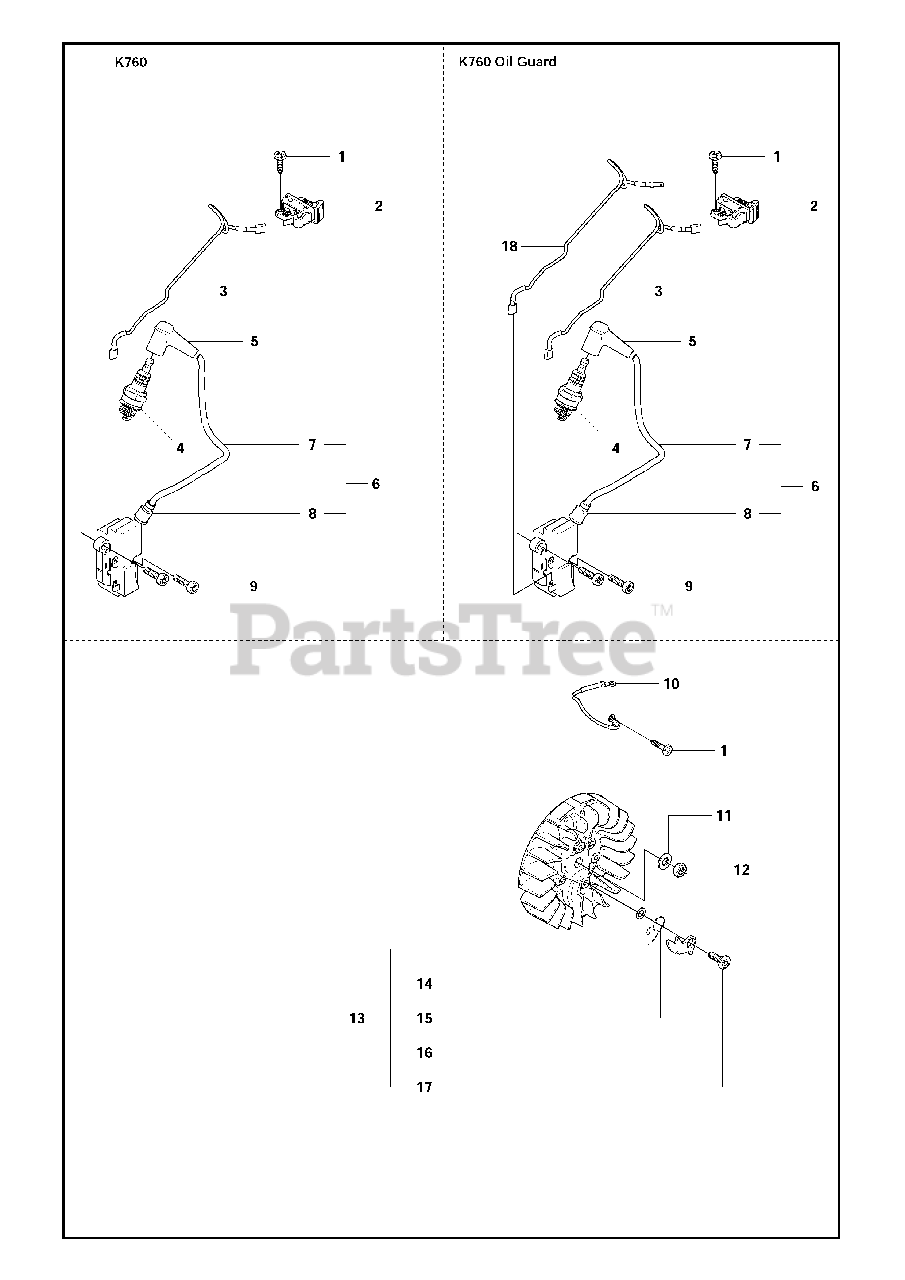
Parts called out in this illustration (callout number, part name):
2	Stop Switch
3	Cable
4	Spark Plug
5	Spark Plug Cap
6	Ignition Module
7	Ignition Cable
8	Isolerhatt
11	Washer Steel
13	Flywheel
14	Washer Steel
17	Screw
18	Cable
